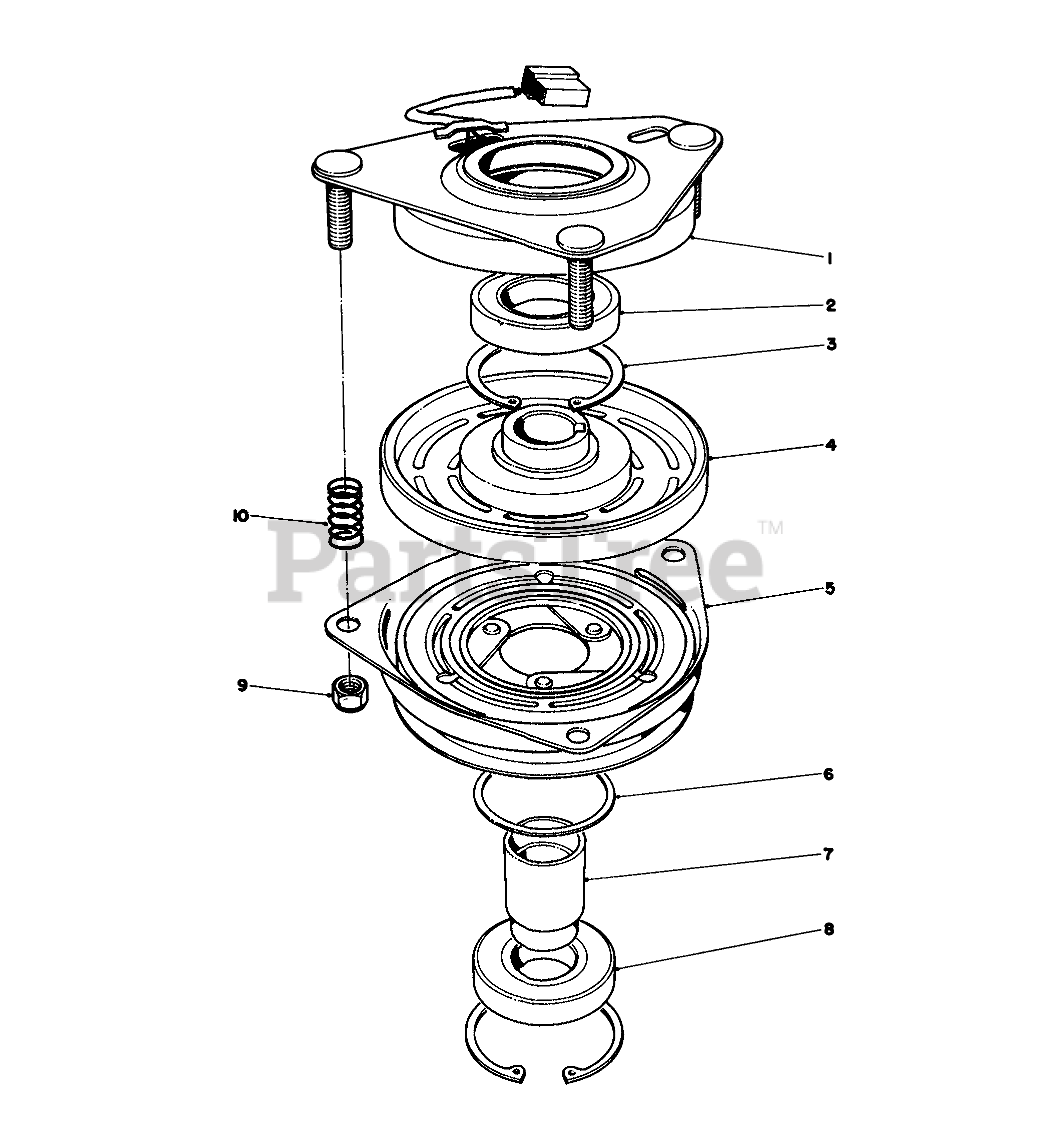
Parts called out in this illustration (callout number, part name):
1	Field Assembly (Incl. Ref. #2 & 3)
2	BEARING-FIELD
3	Retaining Ring
4	Field Coil, Rotor & Bearing Assembly (Incl. Ref. #1)
5	Armature & Pulley Assembly (Incl. Ref. #3, 6, 7 & 8)
6	SPACER-BEARING, PULLEY
7	COLLAR-BEARING
8	BEARING-PULLEY
9	NUT-LOCK
10	SPRING
